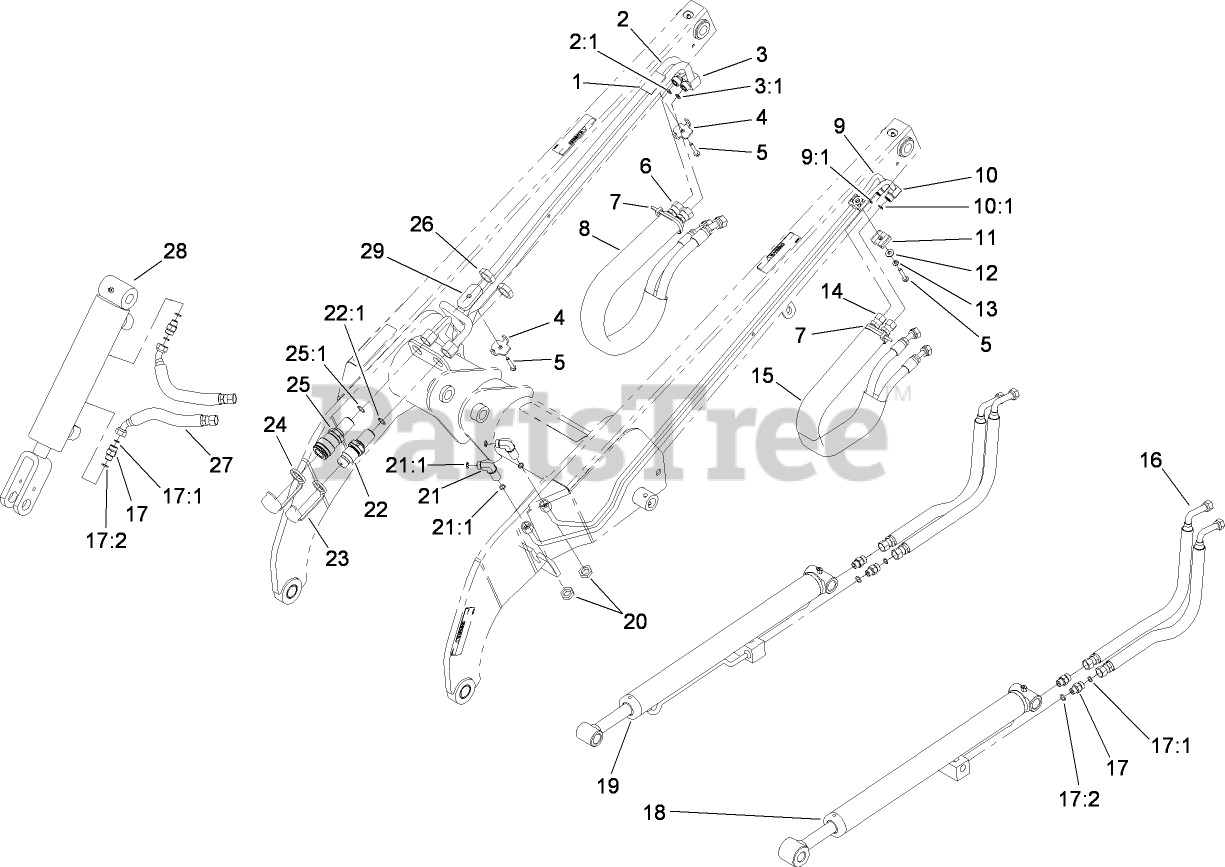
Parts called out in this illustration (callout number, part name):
1	SPACER-HARDLINE
2	HYD TUBE ASM
2:1	O-RING
3	HYD TUBE ASM
3:1	O-RING
4	PLATE-CLAMP, TUBE
5	SCREW-HWH
6	HOSE-HYD
7	TIE-CABLE
8	SLEEVE-PROTECTIVE
9	HYD TUBE ASM
9:1	O-RING
10	HYD TUBE ASM
10:1	O-RING
11	CLAMP-TUBE
12	WASHER-FLAT
13	WASHER-LOCK
14	HOSE-HYD
15	SLEEVE-PROTECTIVE
16	HOSE-HYD
17	FITTING-STRAIGHT
17:1	O-RING
17:2	O-RING
18	LH LIFT CYLINDER ASM
19	RH LIFT CYLINDER ASM
20	NUT-LOCK
21	UNION-BULKHEAD
21:1	O-RING
22	BULKHEAD NIPPLE ASM
22:1	O-RING
23	CAP-DUST, NIPPLE
24	CAP-DUST, COUPLER
25	BULKHEAD COUPLER ASM
25:1	O-RING
26	NUT-LOCK, BULKHEAD
27	HOSE-HYD
28	TILT CYLINDER ASM
29	PLATE-HARDLINE
